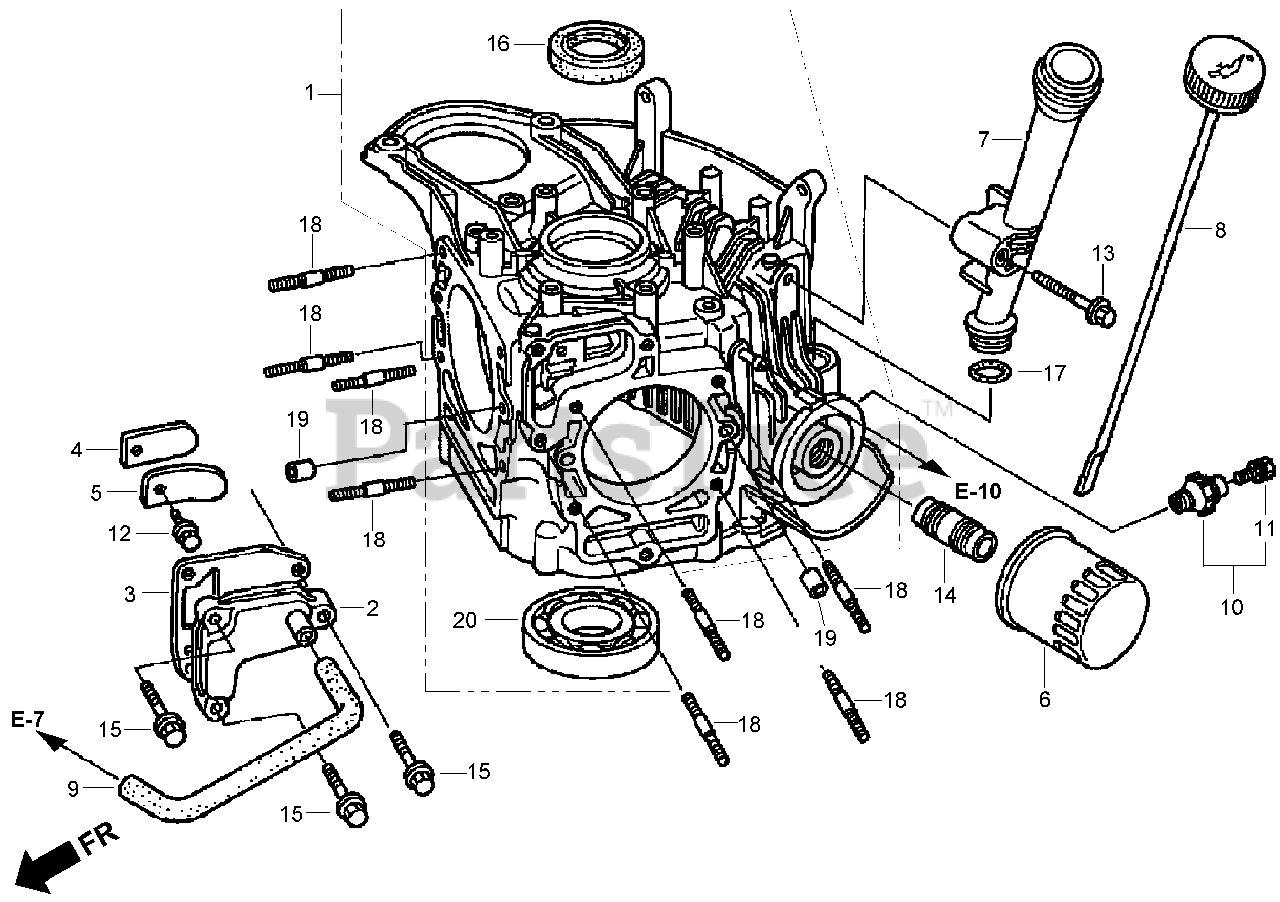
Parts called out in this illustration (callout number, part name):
1	CRANKCASE ASM (840)
2	COVER-BREATHER
3	GASKET-COVER, BREATHER
4	PLATE-VALVE
5	STOPPER-VALVE
6	FILTER-OIL (TOYO ROKI) ( Up To Engine Serial No. 1006029)
6	FILTER, OIL (TOYO ROKI)
7	EXTENSION-FILLER, OIL
8	DIPSTICK-OIL
9	TUBE-BREATHER
10	OIL PRESSURE SWITCH ASM
11	BOLT-WASHER (4X8) (DENSO)
12	BOLT-FLANGE (5X10)
13	BOLT-FLANGE (6X45) (C T200)
14	HOLDER-FILTER, OIL
15	BOLT-FLANGE (6X25) (C T 200)
16	SEAL-OIL (35X5X8)
17	O-Ring (22.5X2.2)
18	BOLT-STUD (8X28)
19	Pin-Dowel (8X14)
20	BEARING-BALL, RADIAL
